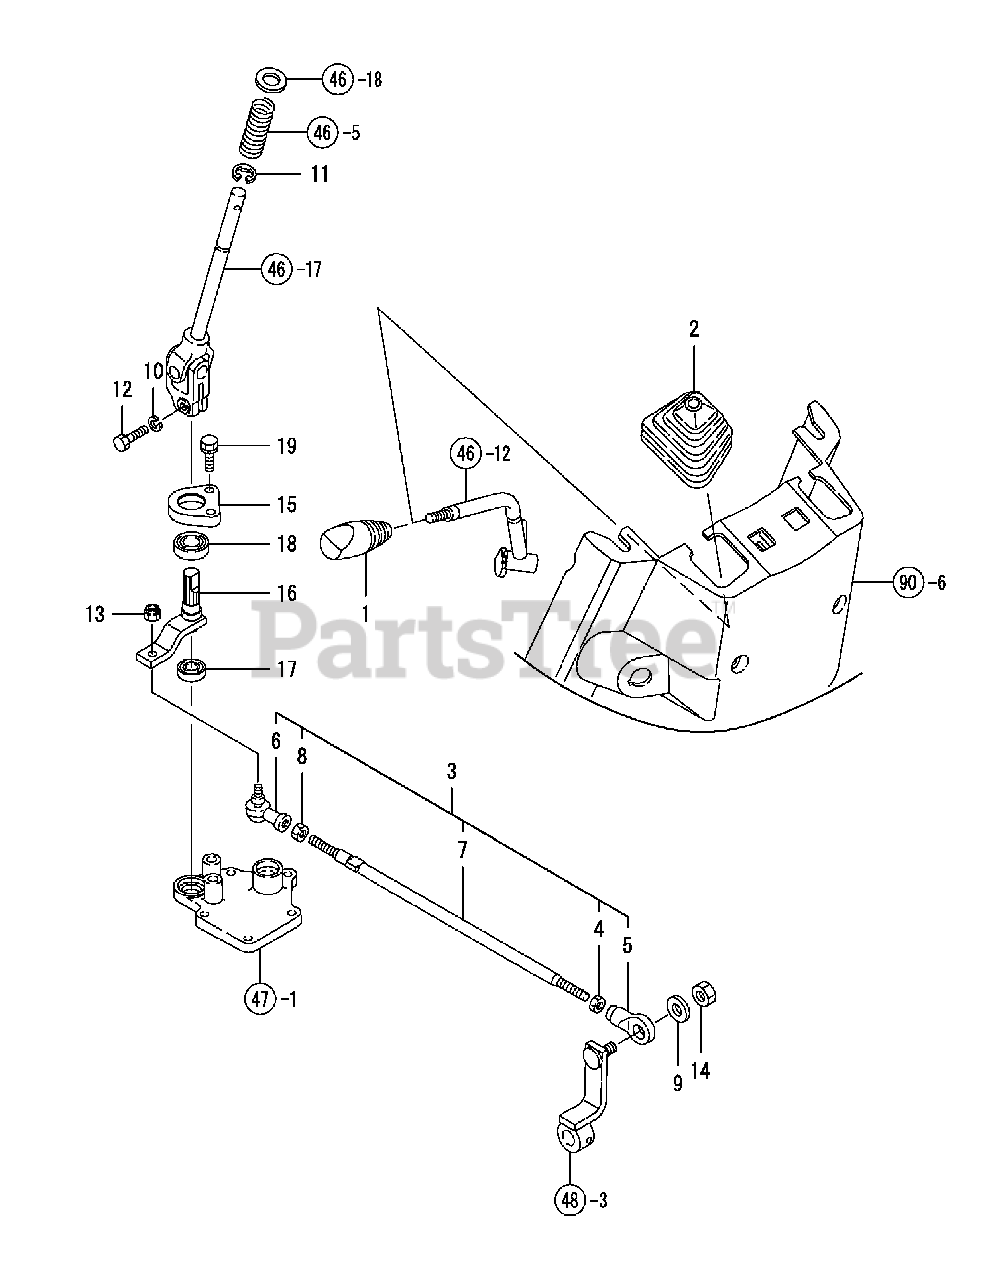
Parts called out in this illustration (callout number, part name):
1	KNOB;REVERSER LEVER
3	ROD COMP.,REVERSER
4	NUT W/WASHER 8
7	SPEED CHANGE ROD
9	WASHER 10,POLISHED
12	BOLT M 8X 25 PLATED
13	U-NUT M 8 PLATED
14	LOCK NUT M10 PLATED
15	HOLDER, REVERSER ARM
16	ARM, LINK REVERSER
17	BALL BEARING 6001UU
